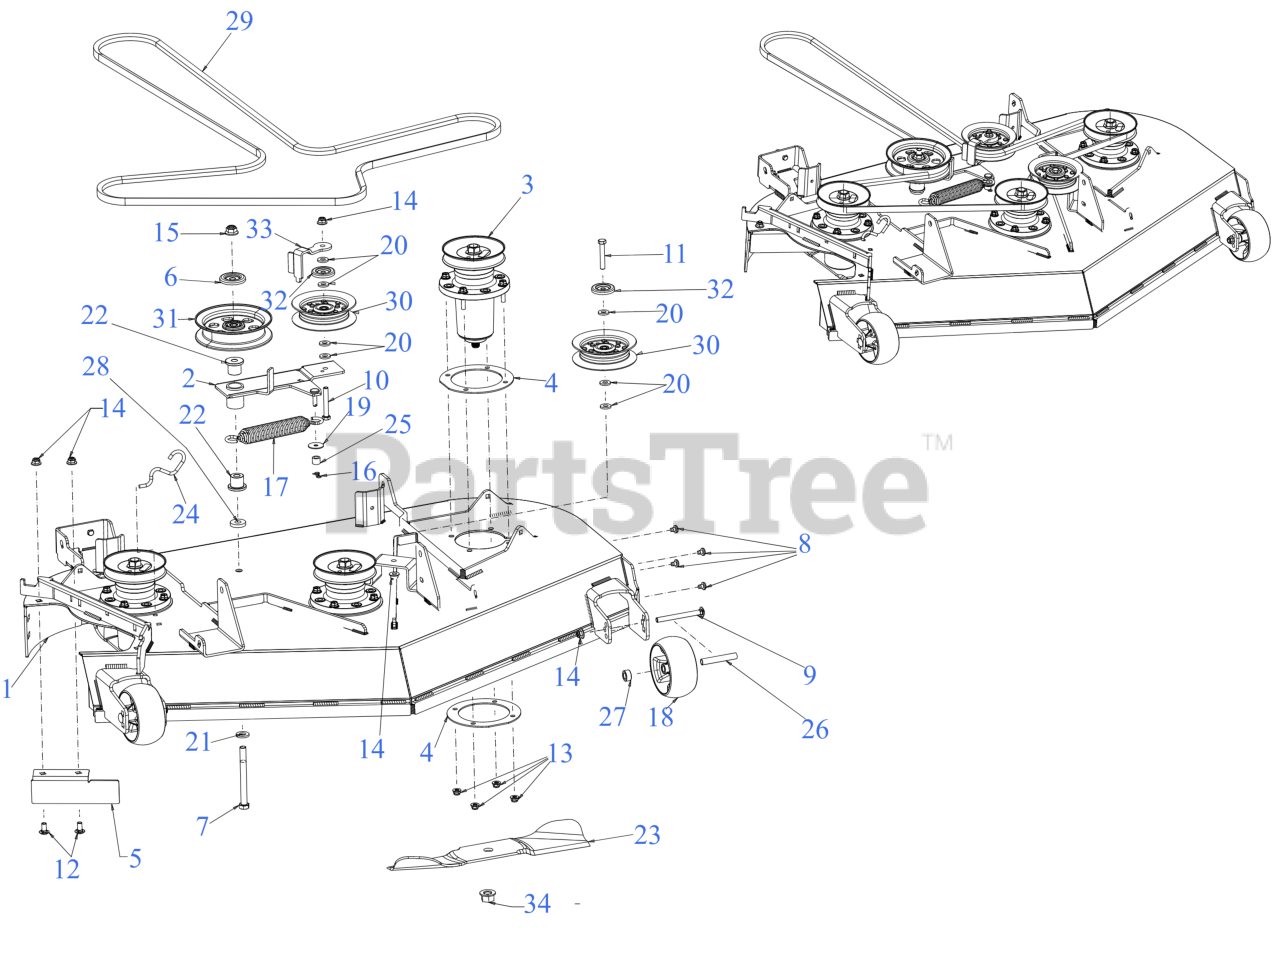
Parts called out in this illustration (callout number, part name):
1	48" FAB DECK SHELL
2	48" DECK IDLER ASSEMBLY
3	SPINDLE ASSEMBLY
4	SPINDLE PLATE
5	48" DECK CHUTE BAFFLE
6	PULLEY CAP (.540 x 2.041 DIA)
7	BOLT-HEX 1/2-13X5.0 GR5
8	SCREW 5/16-18 x .375
9	CARRIAGE BOLT 3/8-16 x 4.00 GR5
10	HEX SCREW-3/8-16X2.5 GR5
11	SCREW 3/8-16 x 2.25 GR5
12	CARRIAGE BOLT 3/8-16 x .75
13	FLANGE LOCK NUT 5/16-18
16	BOW TIE COTTER PIN 1/4-5/16
17	SPRING (1.28" DIA x 8.5" LONG)
18	DECK WHEEL
18	WHEELS-DELUXE 5"
19	FLAT WASHER .322 ID x 1.25 x .060
20	FLAT WASHER
21	FLAT WASHER .531X1.060X.134
22	FLANGE BEARING
23	17" BLADE
24	DECK SPRING HOOK
25	SPACER
26	SPACER .38X.49X3.05LG
27	SPACER-.505 1D
28	SPACER PLATE
29	V-BELT B SEC x 141.50
30	IDLER PULLEY 4.0
31	5" FLAT IDLER PULLEY
32	IDLER PULLEY CAP
33	48" IDLER KEEPER
34	FLANGE NUT - 5/8-18 GDE 8
